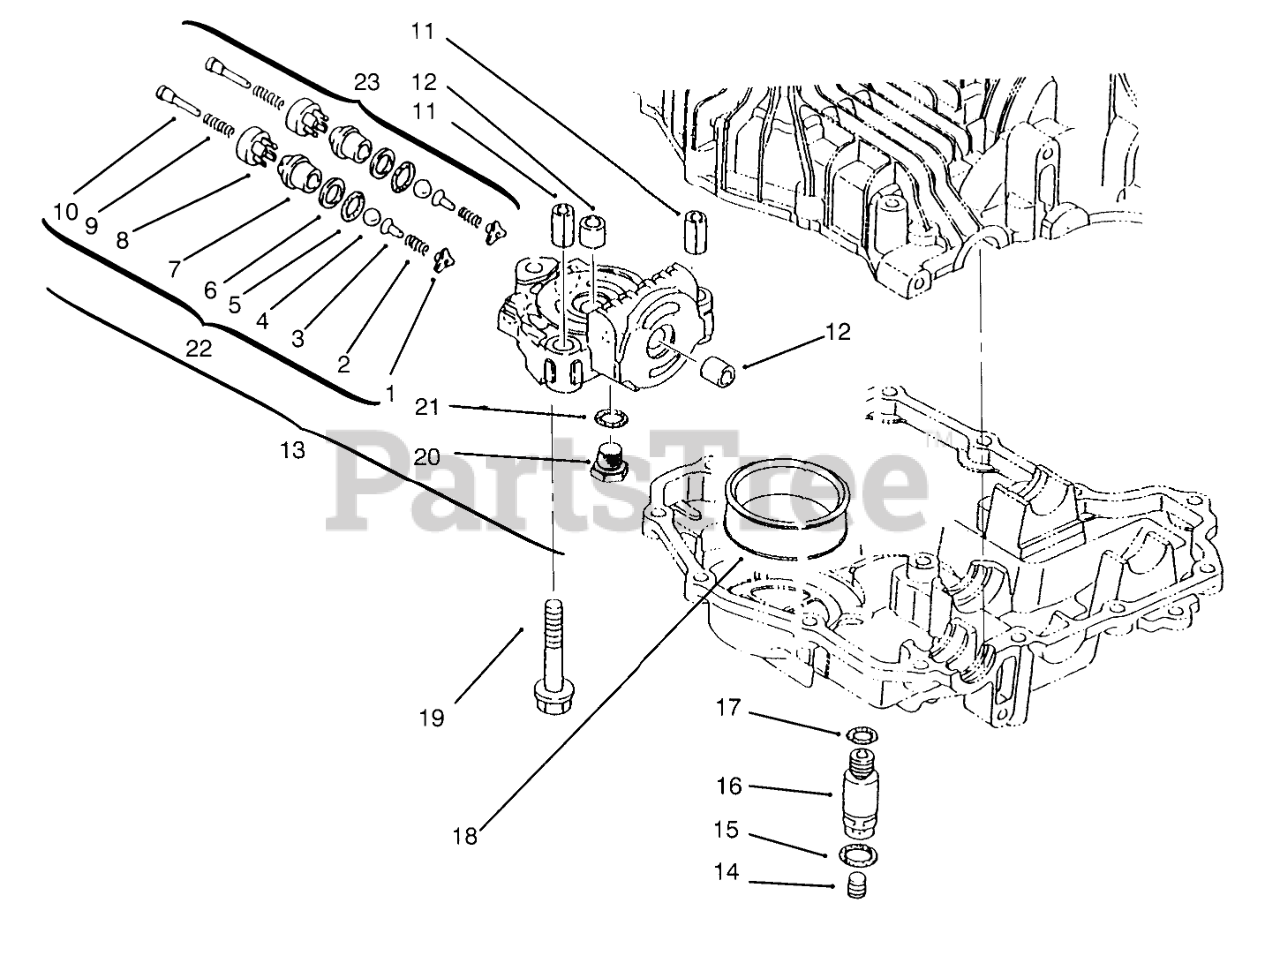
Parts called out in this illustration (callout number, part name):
1	Holder-Bypass
3	Holder-Ball
4	Ball
5	PACKING
6	RING-BACK UP
8	Valve B
10	Pin-Push
11	PIN-KNOCK
12	BUSHING
13	Case INC 11-12 & 20-23
15	PACKING
16	CONNECTOR
17	PACKING
18	FILTER
21	PACKING
22	ASM - VALVE A1 INC 1-10
23	ASM - VALVE A2
